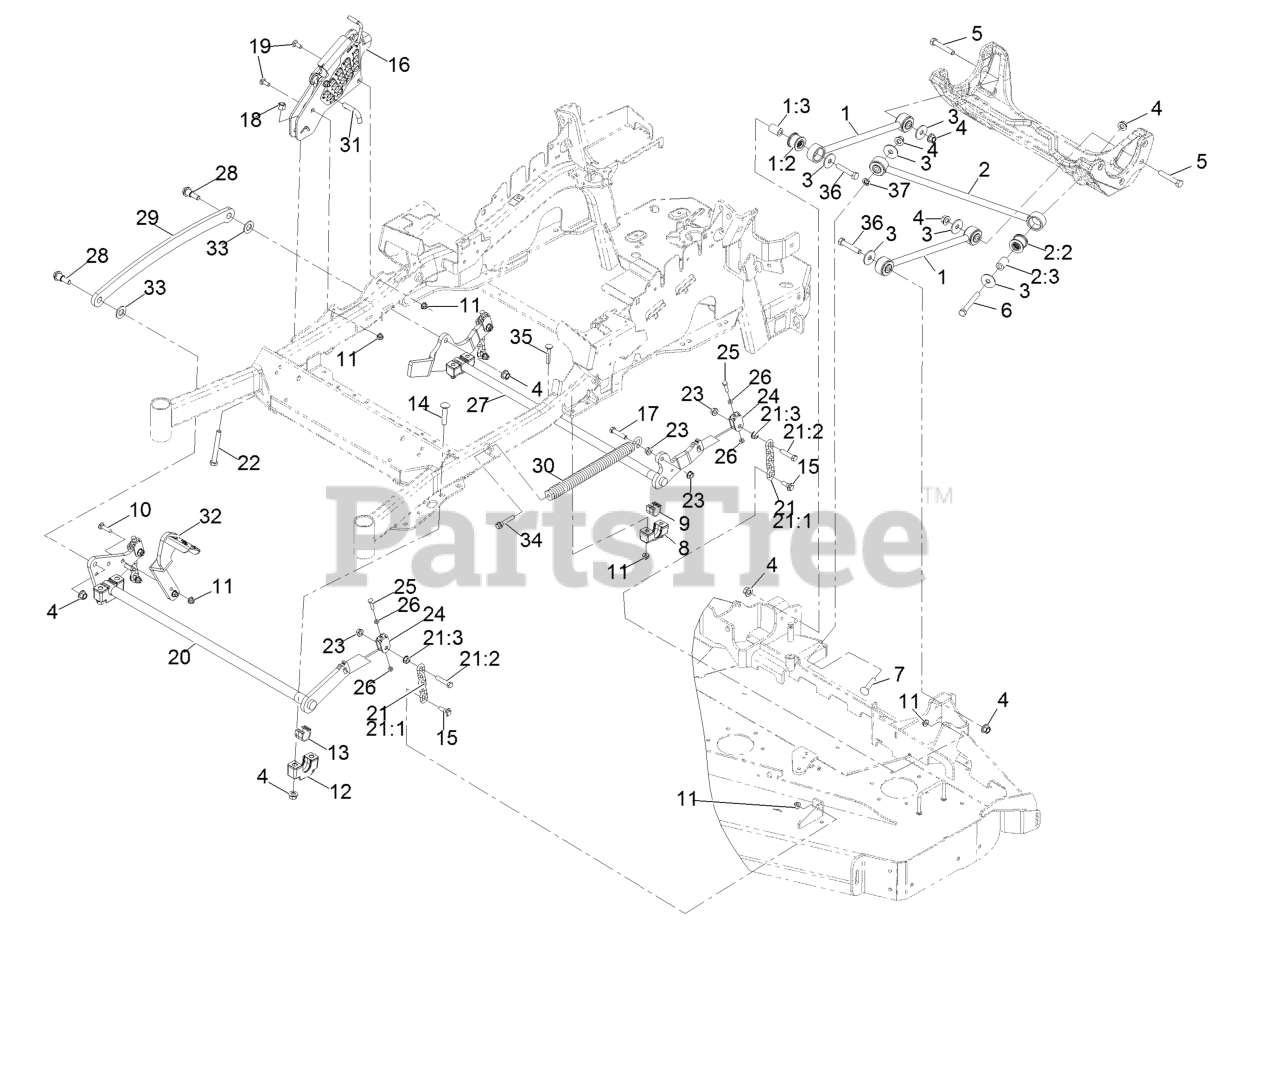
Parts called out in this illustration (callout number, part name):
1	Deck Strut ASM
1:2	Bushing-Suspension, Rubber
2	Panhard Rod ASM
2:2	Bushing-Suspension, Rubber
4	Nut-Lock 1/2-13
5	Screw-HH 1/2-13 X 3
6	Screw-HH 1/2-13 X 4
7	Bolt-Carriage 1/2-13 X 2 1/2
8	Support-Cross Shaft, Bearing Rear
9	Bearing-Cross Shaft, Rear
10	Bolt-Carriage 3/8-16 X 1 1/2
11	Nut-Nyloc 3/8-16 Flg
12	Support-Cross Shaft, Bearing
13	Bearing-Cross Shaft, Front
14	Bolt-Carriage 1/2-13 X 2 1/2 Spl Neck
15	Screw-Hex Flange 3/8-16 X .80
16	HOC ASM
17	Screw-HH 7/16-14 X 2
18	Nut-Nyloc 1/2-13
19	Bolt-Carriage 3/8-16 X 1
20	Decklift-Front
21	Deck Lift Chain ASM
21:1	Chain-Lift, Deck
21:2	Screw-HH 7/16-14 X 2
21:3	Nut-Whizlock 7/16-14
22	Bolt-HH 1/2-13 X 4 Tap
23	Nut-Whizlock 7/16-14
24	Yoke-Adjust, Deck
25	Screw-HH 5/16-18 X 1 1/4
26	Nut-Jam 5/16-18
27	Lift-Deck, Rear
28	Screw-Shoulder HHF 1/2-13 X 1.12
29	Link-Lift, Deck
30	Spring-Extension
31	Pin-HOC
32	Lever-Foot
33	Washer-3/4 SAE
34	Screw-Shcs 3/8-16 X 2.212
35	Bolt-Carriage 3/8-16 X 2 1/4
36	Screw-HH 1/2-13 X 2 3/4
37	Nut-Push
